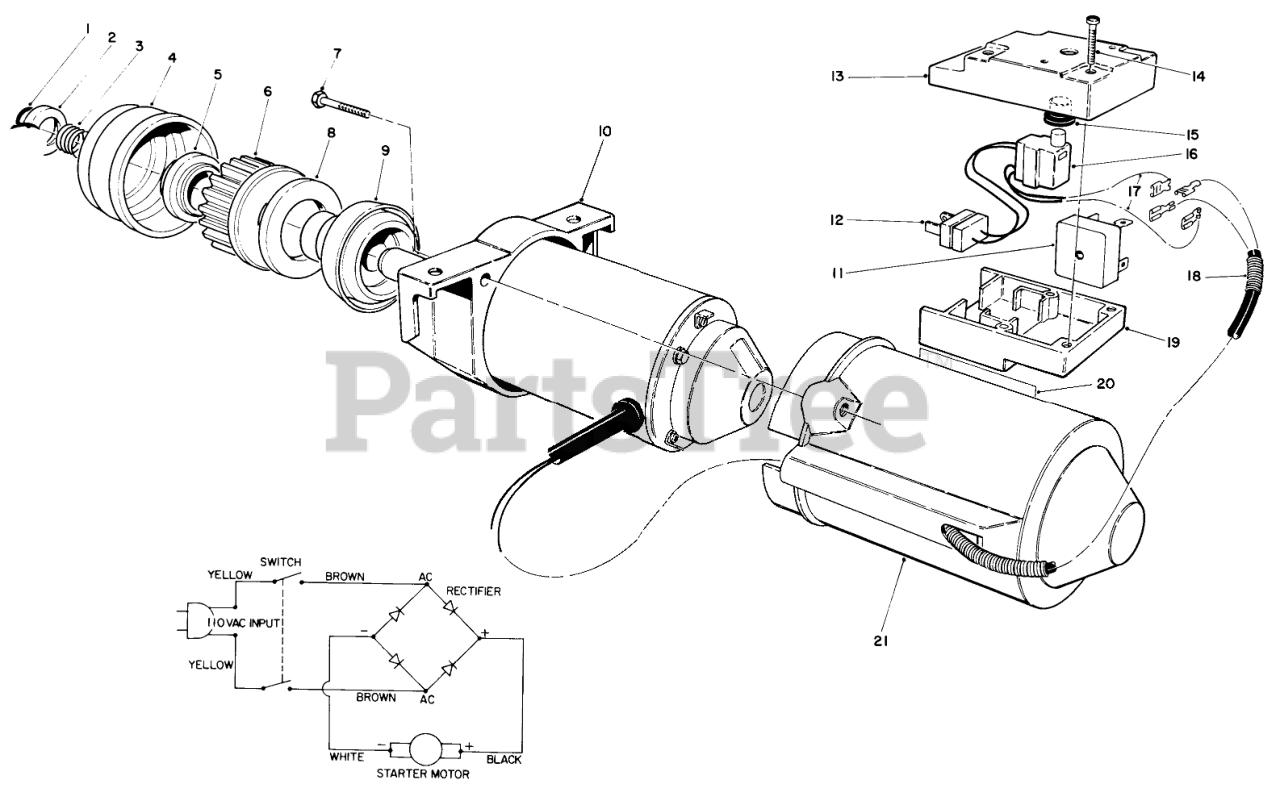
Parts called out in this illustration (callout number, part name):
1	RING-LOCK
2	PINION STOP
3	SPRING
4	Retainer
5	Bushing
6	Gear-Pinion
7	Screw-Plastite
8	Ring-Rubber
9	Drive-Pinion
10	Starter Motor Assembly (Incl. Ref. #1-6, 8 & 9)
11	RECTIFIER-BRIDGE
12	Plug
13	SWITCH BOX CAP
14	SCREW
15	BOOT-SWITCH
16	SWITCH-STARTER
18	CABLE COVER
19	SWITCH BOX BASE
20	Decal-UL
21	STARTER MOTOR COVER
